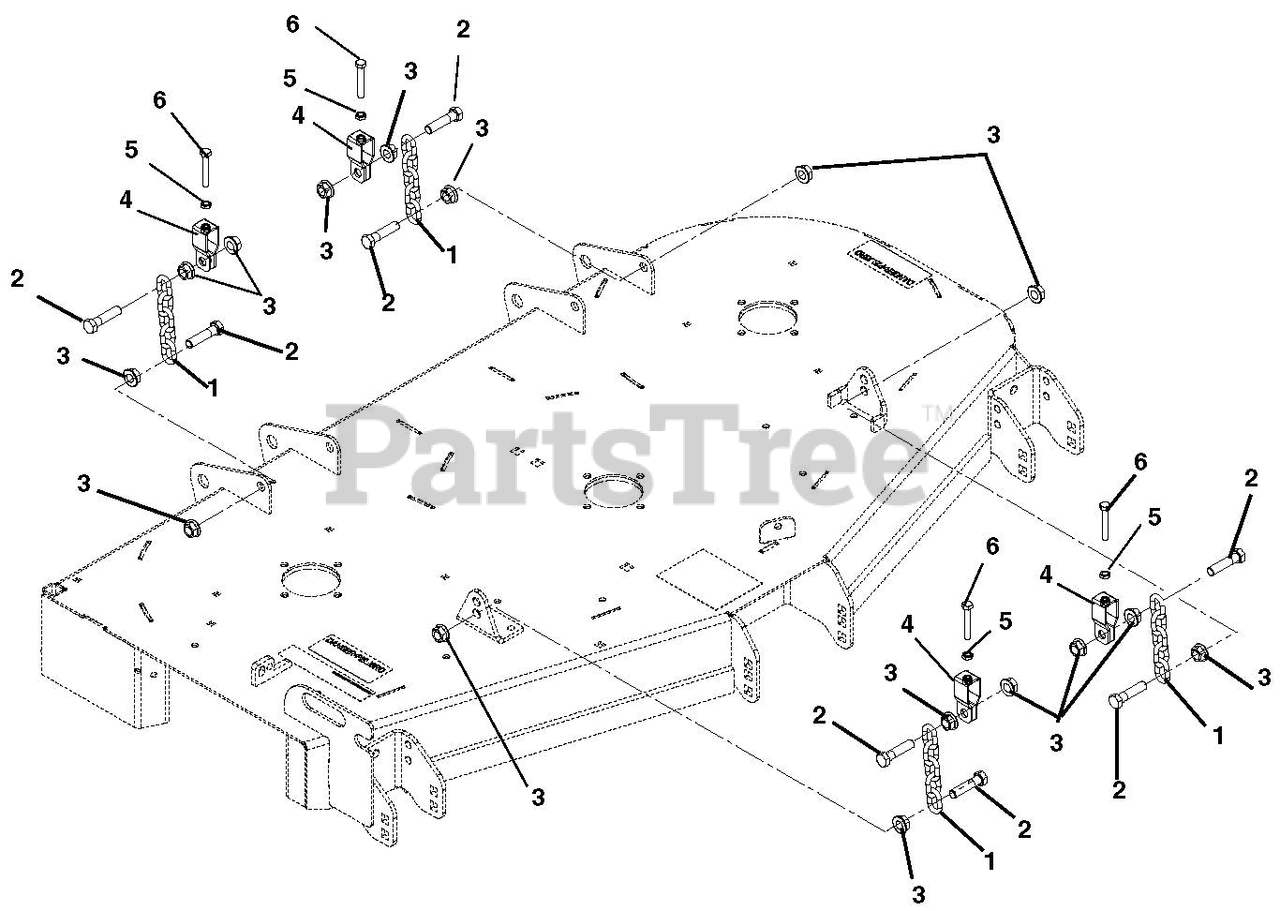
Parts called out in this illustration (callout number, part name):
1	CHAIN, LINK
2	BLT, HEX M12-1.75X50 CLS8.8 YZ
3	NUT-SPNLK-FLG M12-1.75 YZ
4	BRKT, DECK LEVELING
5	NUT- JAM .312-18 YWZC
6	BLT-HEX .312-18X2.00 FTH GR5YZ
